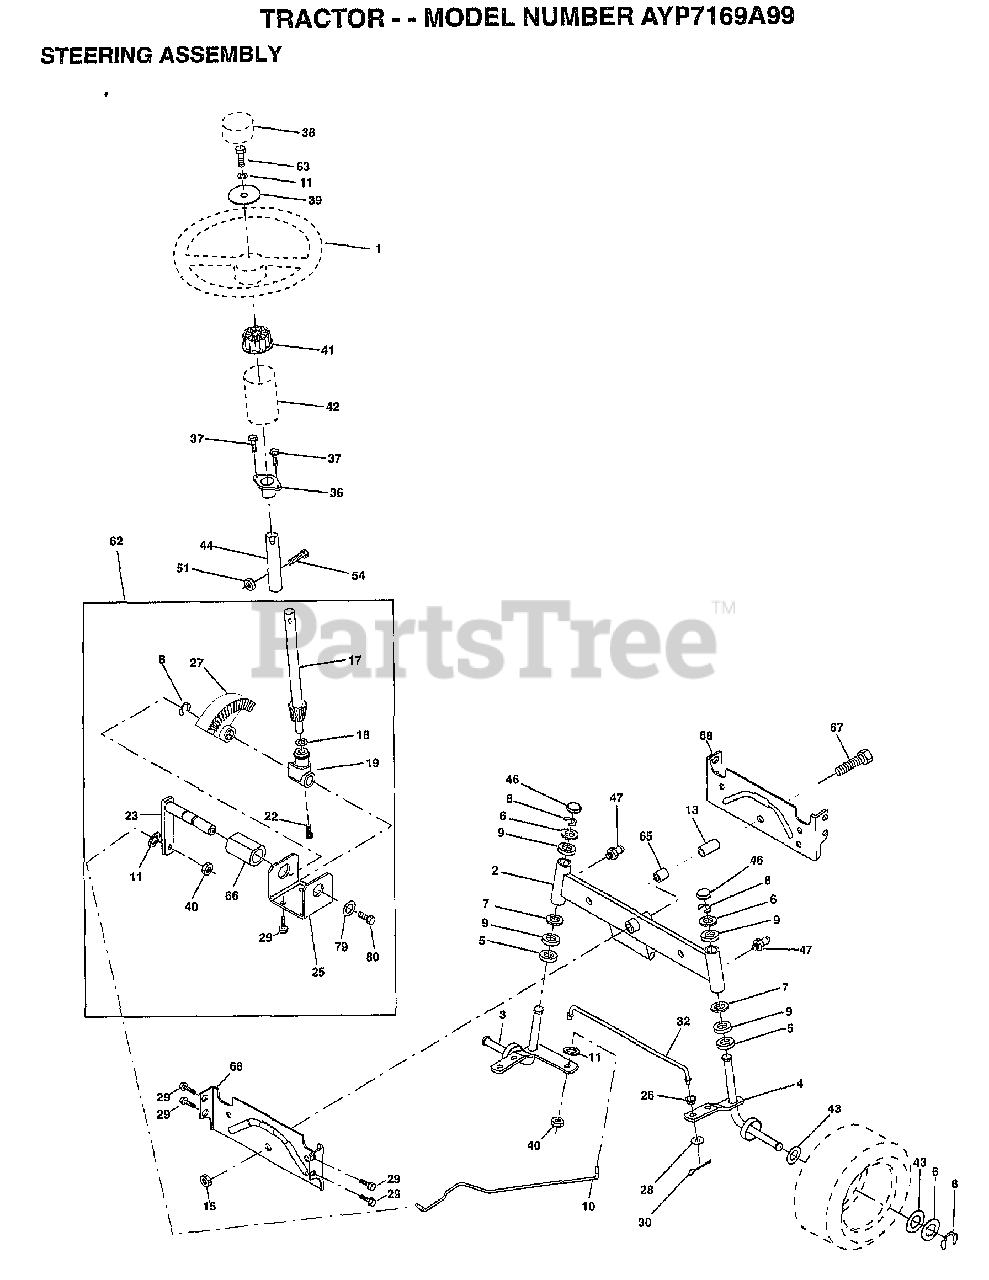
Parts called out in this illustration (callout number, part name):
1	WHEEL STR AYP BLK
2	AXLE ASM
3	SPINDLE.ASM.LH
4	"SPINDLE ASM,RH"
5	WASHER .T
6	WASHER
7	WASHER
8	RING
9	COL. SRTG. BEAR.
10	DRAGLINK-STAMPED
11	LOCKWASHER
13	BEARING AXLE
15	"NUT-LOC,FLANGE LT"
17	SHAFT ASM STEERIN
18	THRUST WASHER
19	SUPPORT.SHAFT.STEER
22	SCREW.HX.WSH.HD
23	SHAFT.ASM.PITMAN
25	BRKT-STEERING
26	BUSHING.DRAGLINK
27	GEAR SECTOR
28	WASHER
29	SCREW
30	COTTER PIN
32	TIE ROD
36	BUSHING.STEERING
37	"SCREW-TT,10-32 FL"
38	CAP STEER AYP
39	WASHER T
40	GRIPCO NUT
41	ADAPTER LT
42	BOOT.STEER.PL
43	WASHER
44	EXT SHAFT STEERIN
46	CAP
47	ZERK M
51	NUT
54	BOLT
62	KIT.STEER.ASM
63	BOLT
65	SPACER AXLE
66	"BEARING-ARM,PITMA"
67	BOLT
68	BRACE AXLE
79	WASHER
80	BOLT.HX.NYLON3/8-16X3/
